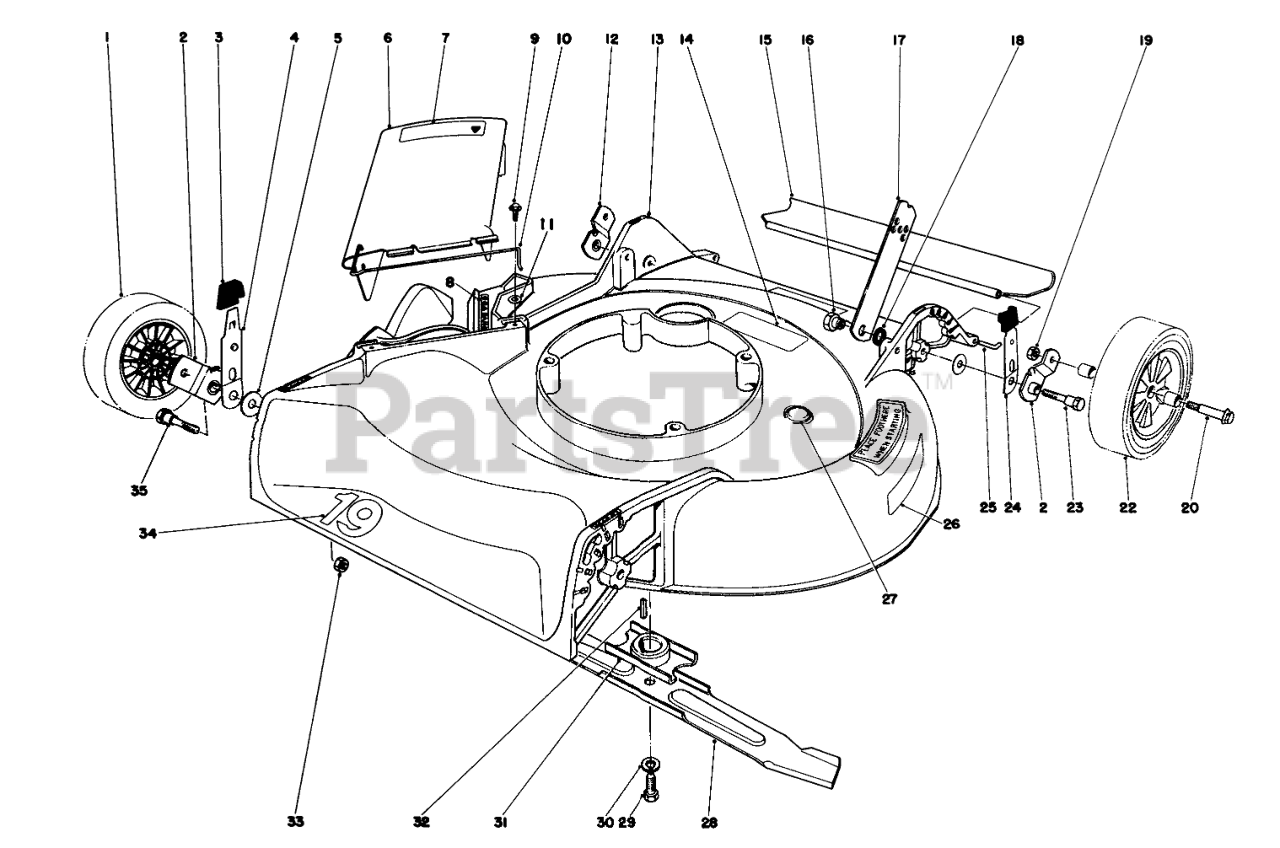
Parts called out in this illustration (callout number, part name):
1	WHEEL TIRE ASM 7 IN
2	Pivot Arm
3	Knob Arm
4	SPRING ARM ASM
5	WASHER-PIVOT
6	Deflector-Cover Assembly (Incl. Ref. #7 & 10)
7	Decal-Caution
8	Decal-Danger
9	SCREW
10	SPRING HINGE
11	WASHER-FLAT
12	Pivot Arm
13	Housing (Model 16077)
14	Decal-Warning
15	SHIELD - TRAILING
16	HANDLE PIVOT NUT
17	Handle Latch
18	HANDLE LATCH SPACER
19	Nut
20	BOLT-WHEEL
22	WHEEL TIRE ASM 8 IN
23	PIVOT SCREW
24	SPRING ARM ASM
25	SHIELD ROD
26	Decal-Step
28	Blade
29	SPECIAL SCREW
30	WASHER-LOCK
31	Blade Retailer
32	KEY-SQUARE
33	Nut
34	Decal-19" (Model 16077)
35	PIVOT SCREW
